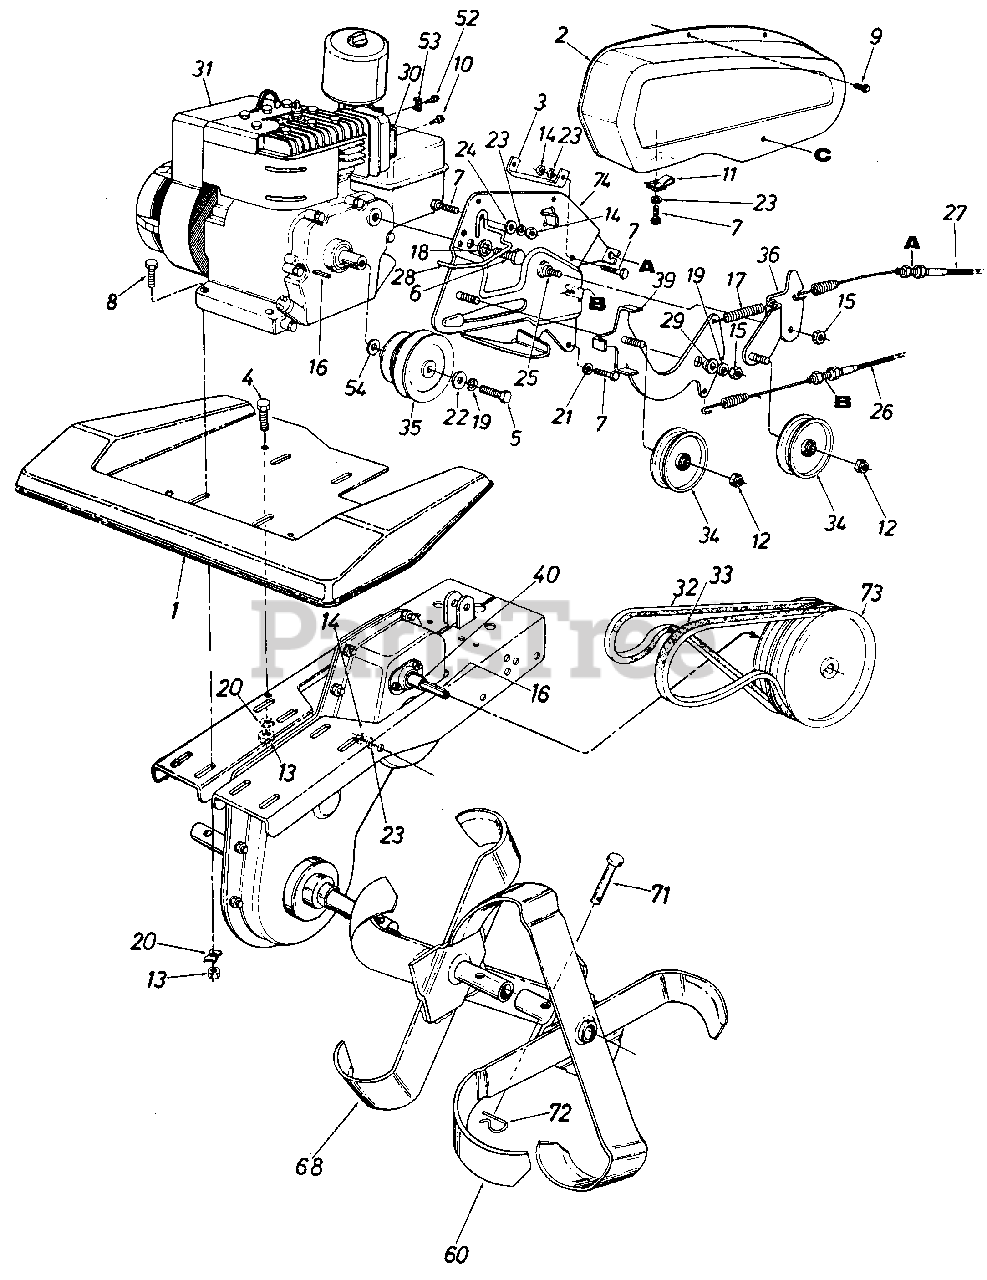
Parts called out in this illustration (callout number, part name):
4	SCREW-HEX 5/16-18 X .75
5	SCREW 3/8-24X1.25 GR5
6	SCREW-HEX 5/16-24 X .62
7	SCREW-HEX 1/4-20 X .75
8	SCREW-HEX 5/16-18 X 1.50
9	SCREW-HEX WASH SF TAPP
10	SCREW-HEX WASH HD 10-32X.38
11	NUT-SPEED-1/4-20
12	NUT-HEX CENTER JAM 3/8-24
13	NUT-HEX 5/16-18
14	NUT-HEX 1/4-20
15	NUT-HEX CENTER L-3/8-16
16	KEY-SQ 3/16X1.50
17	SPRING-EXTENSION
18	WASHER-LOCK-5/16
19	WASHER-LOCK-3/8
20	WASHER-SPEC L 5/16 X .88 OD
21	WASHER-SPRING.270 ID X.51 OD X.030
22	WASHER-FL-.385 X 1.00 X .135
23	LOCK WASHER 1/4 DIA
24	WASHER-FL
25	SCREW-SHLD .625 DIA X .163
26	CABLE-CLUTCH CONTROL
27	CABLE-CLUTCH CONTROL
28	ROD-BELT GUARD
29	SPACER-SHLD
30	DEFLECTOR-MUFFLER
32	BELT-V 1/2 X 41
33	BELT-V 1/2 X 37 SPECIAL
34	PULLEY-IDLER-FLAT W/FLANGES
35	PULLEY-ENGINE
36	BRACKET ASSY-IDLER
39	BRACKET ASSY-IDLER
40	SPACER-.635 ID X .88 OD X 1.03
52	SCREW-HEX SEMS #10-32
53	CLAMP-CASING
54	WASHER-FL
68	TINE ASSY-INNER-LH
71	PIN-CLEVIS
72	PIN-COTTER
74	PLATE ASSY-MTG
